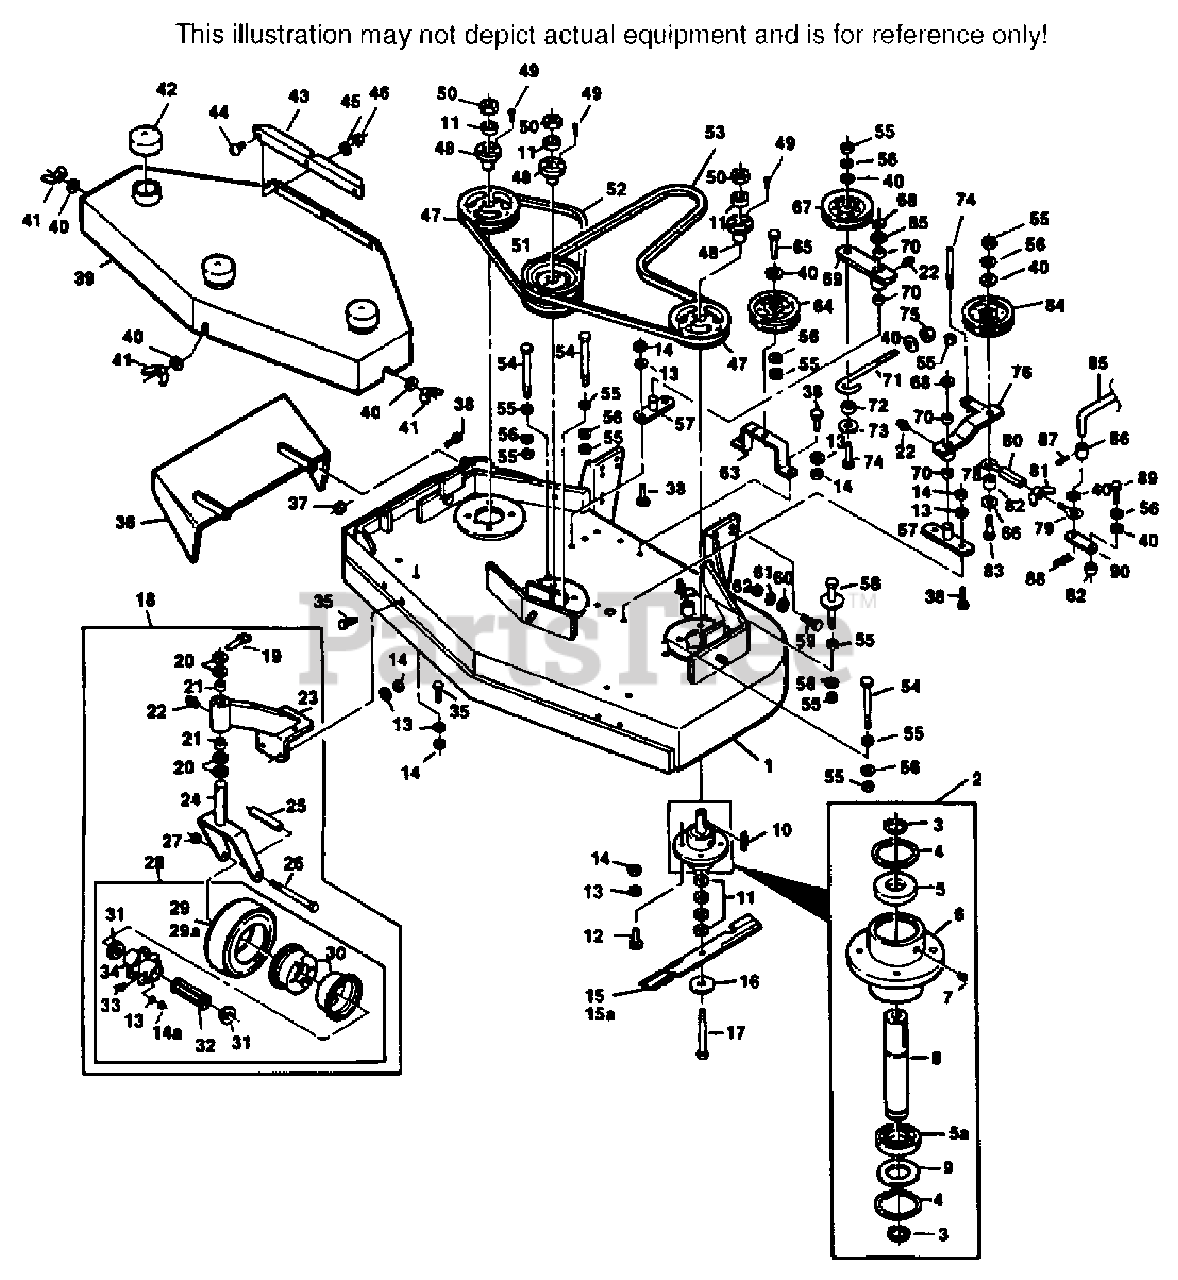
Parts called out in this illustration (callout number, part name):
1	CUTTER DECK WLD(INCL. DECALS)
2	CUTTER SPINDLE ASSY.(INCL. 3-9)
3	RETAINING RING, 1" EXT.-INVERTED
4	RETAINING RING, 2-7/16 INT.-BASIC
5	BEARING, CUTTER SPINDLE
6	SPINDLE HOUSING
7	GREASE FITTING, STR. 5/16 SERR.
8	SPINDLE, CUTTER BLADE
9	WASHER, 1-15/16 X 2-13/32 X 16 GA.
10	KEY, 1/4 X 1/4 X 2
11	SPACER, CUTTER BLADE
15	CUTTER BLADE, 16-1/2" STD.
15A	CUTTER BLADE, 16-1/2" HIGH LIFT
16	FLAT WASHER, 5/8W
17	HEX HEAD BOLT, 5/8-11 X 9-1/2
18	CASTER ASSY, COMP.(INCL. 19-28)
19	QUICK PIN
20	SPACER, CASTER YOKE, 1/2 LONG
21	BRONZE BEARING
22	GREASE FITTING, STR. 1/4-28
23	SUPPORT ASSY.(INCL. 21-22)
24	CASTER YOKE WLD.
25	SLEEVE, CASTER WHEEL BEARING
26	HEX HEAD BOLT, 1/2-13 X 5-1/2
28	WHEEL ASSY.(INCL. 13-14, 29-34)
29	TIRE ONLY, CASTER WHEEL
29A	INNER TUBE ONLY, CASTER WHEEL
30	RIM PAIR, CASTER WHEEL
31	RETAINER, BEARING, CASTER WHEEL
32	ROLLER BEARING, CASTER WHEEL
33	GREASE FITTING, 45' 1/4-28
34	HUB ASSY. W/BOLTS, CASTER WHEEL
36	DISCHARGE CHUTE WLD.
37	HEX NUT, 5/16-18 ELASTIC STOP
39	BELT COVER ASSY.(INCL. DECALS)
40	WASHER, 25/64 X 15/16 X 12 GA.
41	WING NUT, 3/8-16
42	SPINDLE SHIELD
43	BELT COVER SKIRT
47	PULLEY(INCL. 48-49)
48	TAPER HUB
51	PULLEY, DOUBLE(INCL. 48-49)
52	BELT, RH BLADE DRIVE
53	BELT, BLADE DRIVE
57	IDLER PIVOT WLD.
58	BELT GUIDE WLD.
60	WASHER, 15/32 X 59/64 X 16 GA.
62	HEX NUT, 7/16-14, ELASTIC STOP
63	IDLER PULLEY SUPPORT
64	PULLEY, BELT GUIDE
66	WASHER, 13/32 X 13/16 X 16 GA.
67	IDLER PULLEY, "V" GROOVE
68	RETAINING RING, 3/4 EXT.-"E"69
69	IDLER ARM ASSY.(INCL. 22 & 70)
70	BRONZE BEARING
71	ROD, IDLER PULL, J
72	SPACER, J PULL ROD
73	WASHER, 3/8 X 1-1/2 X 16 GA.
75	HEX NUT, 3/8-16 ELASTIC STOP
76	IDLER ARM ASSY.(INCL. 22 & 70)
79	EYEBOLT, RH
80	TURNBUCKLE
81	WING NUT, 5/16-18
82	SLEEVE, CAM CLUTCH
84	IDLER PULLEY, BELT CLUTCH - STD.
84	IDLER PULLEY, BELT CLUTCH - WIDE
85	BLADE CLUTCH ROD
86	SLEEVE, CLUTCH ROD
88	HAIR PIN, LARGE
90	CAM LINK WLD.
